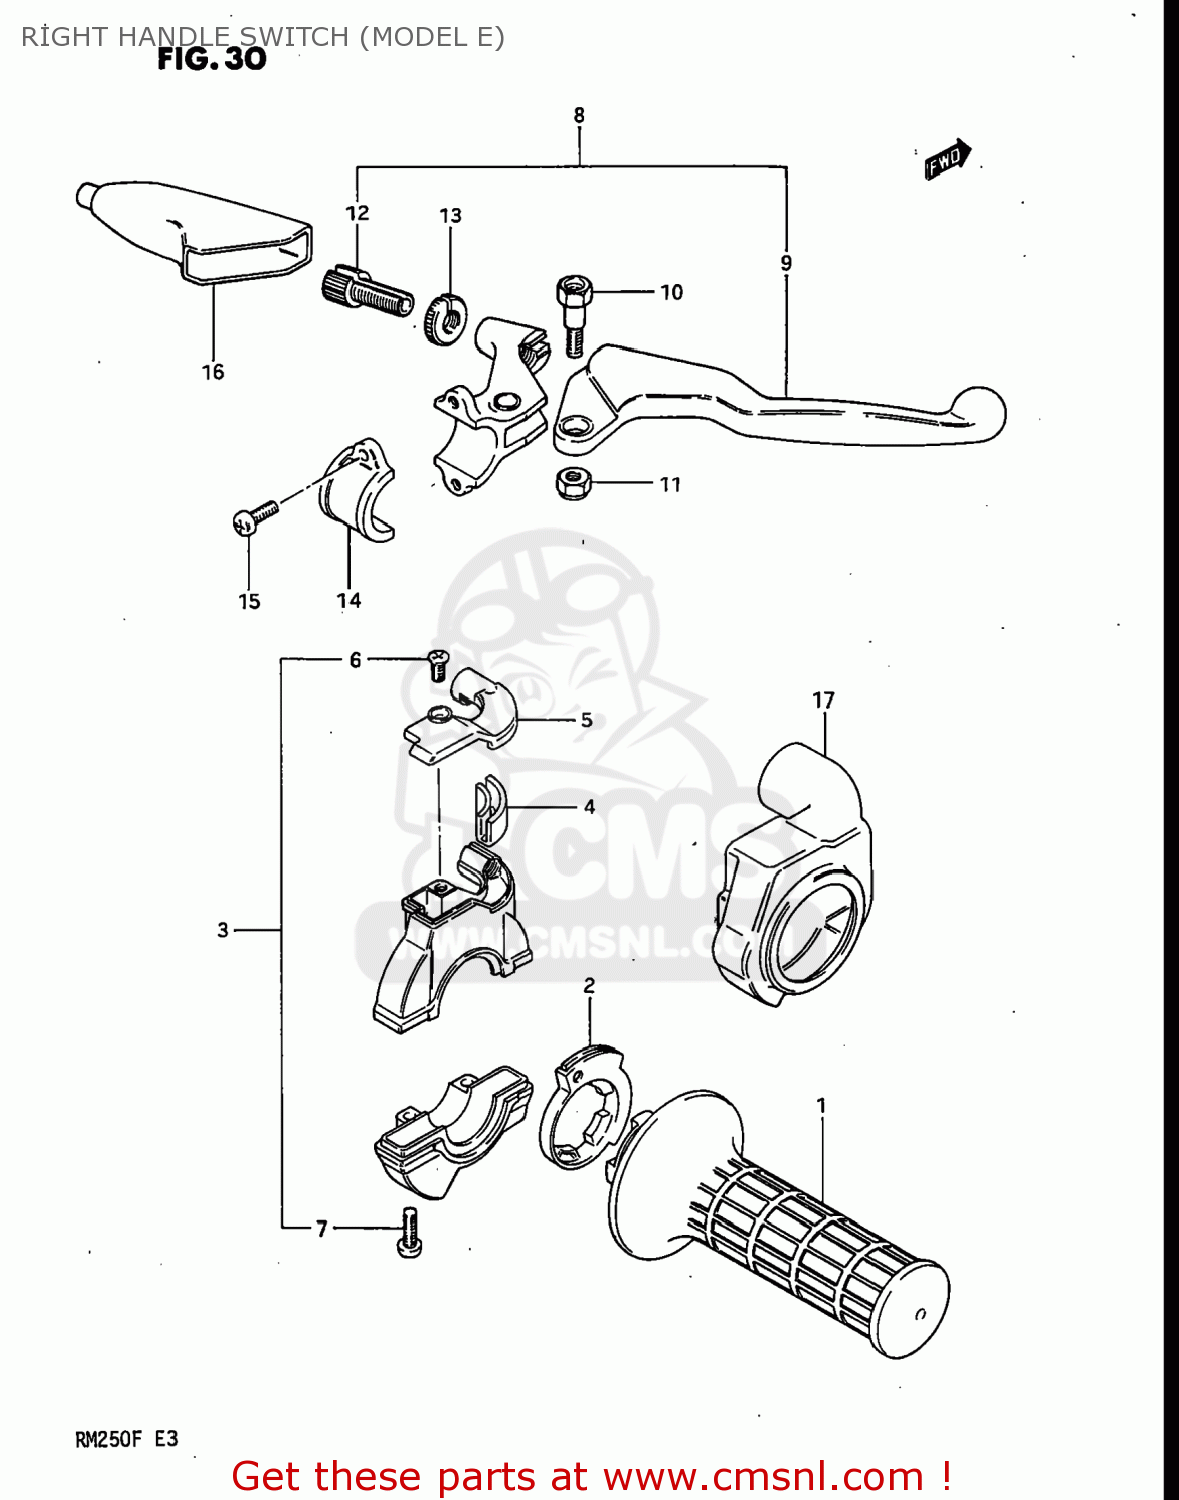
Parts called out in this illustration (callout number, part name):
1	GRIP,THROTTLE
2	ROTOR,THROTTLE GRIP
3	CASE ASSY,THROTTLE
4	GUIDE PIECE,THROTTLE
5	COVER,THROTTLE CASE
6	SCREW
7	SCREW
8	LEVER ASSEMBLY,BRAKE
9	LEVER,BRAKE
10	BOLT,LEVER
11	NUT 6MM
12	ADJUSTER,CABLE
13	NUT,CABLE ADJUSTER
14	BRACKET,CLUTCH LEVER HOLDER
15	SCREW
16	COVER,CLUTCH LEVER
17	COVER,THROTTLE CASE
